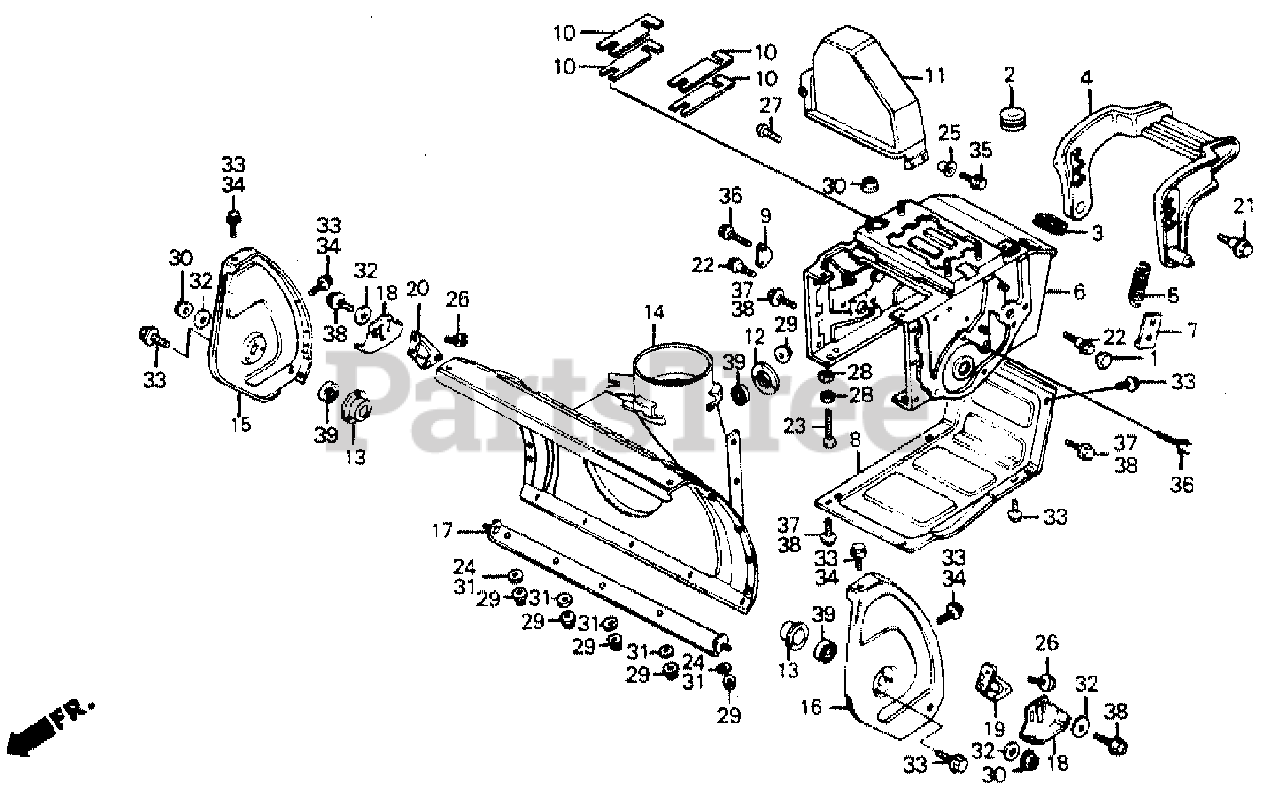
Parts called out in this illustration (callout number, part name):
1	GROMMET, GUIDE ROLLER
2	GROMMET A, TUBE
3	SEAL, CHANGE ROD
4	PLATE, HEIGHT ADJUSTING (NOT AVAILABLE)
5	SPRING, HEIGHT ADJUSTING
6	BED, ENGINE
7	HOOK, SPRING (NOT AVAILABLE)
8	COVER (LOWER) (NOT AVAILABLE)
9	PLATE, DISK HOLDER SHAFT
11	COVER, BELT (NOT AVAILABLE)
12	HOLDER, L. AUGER
13	HOLDER, AUGER BEARING
14	HOUSING, AUGER (12")
15	COVER, R. AUGER SIDE
16	COVER, L. AUGER SIDE (NOT AVAILABLE)
17	GUARD, AUGER HOUSING
18	SKID, AUGER
19	STAY, L. SKID (12) (NOT AVAILABLE)
20	STAY, R. SKID (12) (NOT AVAILABLE)
21	BOLT, HEIGHT ADJUST SETTING
22	BOLT, TRANSMISSION SETTING
23	BOLT, ADJUSTING
24	WASHER (6X17)
25	WASHER, CHAIN CASE SETTING
26	BOLT-WASHER (6X14)
27	SCREW, PAN (6X18)
28	NUT, HEX. (8MM)
29	NUT, FLANGE (6MM)
30	NUT, FLANGE (8MM)
31	WASHER, PLAIN (6MM)
32	WASHER, PLAIN (8MM)
33	BOLT, FLANGE (6X10)
34	BOLT, FLANGE (6X12)
35	BOLT, FLANGE (6X14)
36	BOLT, FLANGE (6X18)
38	BOLT, FLANGE (8X16)
39	BEARING, RADIAL BALL (6203UU)
